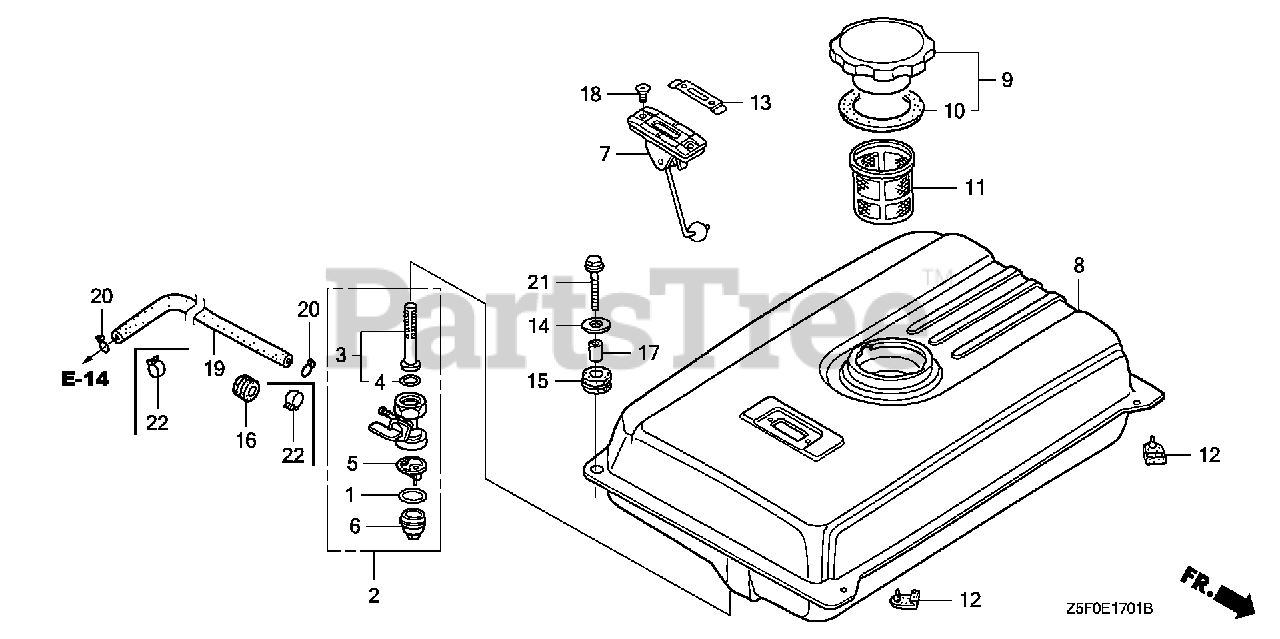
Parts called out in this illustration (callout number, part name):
1	GASKET, FUEL STRAINER CUP
2	PETCOCK ASSY.
3	SCREEN SET, FUEL STRAINER
4	O-RING (9.0X1.3)
5	FILTER, CUP
6	CUP, FUEL STRAINER
7	METER ASSY., FUEL
8	TANK, FUEL *NH31* (MCKINLEY WHITE)
8	TANK, FUEL *NH1* (BLACK)
8	TANK, FUEL *T68* (TSURUMI BLUE)
8	TANK, FUEL *Y131* (LIGHTNING YELLOW)
8	TANK, FUEL *R280* (POWER RED)
9	CAP, FUEL FILLER
10	GASKET, FUEL FILLER CAP
11	FILTER, FUEL
12	RUBBER, TANK MOUNTING
13	PLATE, FUEL INDICATION
14	WASHER, TANK CUSHION
15	RUBBER, TANK CUSHION
16	RUBBER, FUEL (9X15X10)
17	COLLAR, TANK CUSHION
18	SCREW, FLAT (5X10)
19	TUBE, FUEL (4.5X180) (FKM)
19	BULK HOSE, FUEL (4.5X3000) (4.5X180)
20	CLIP, TUBE (B8)
21	BOLT, FLANGE (6X22)
22	CLAMP, TUBE (D8)
